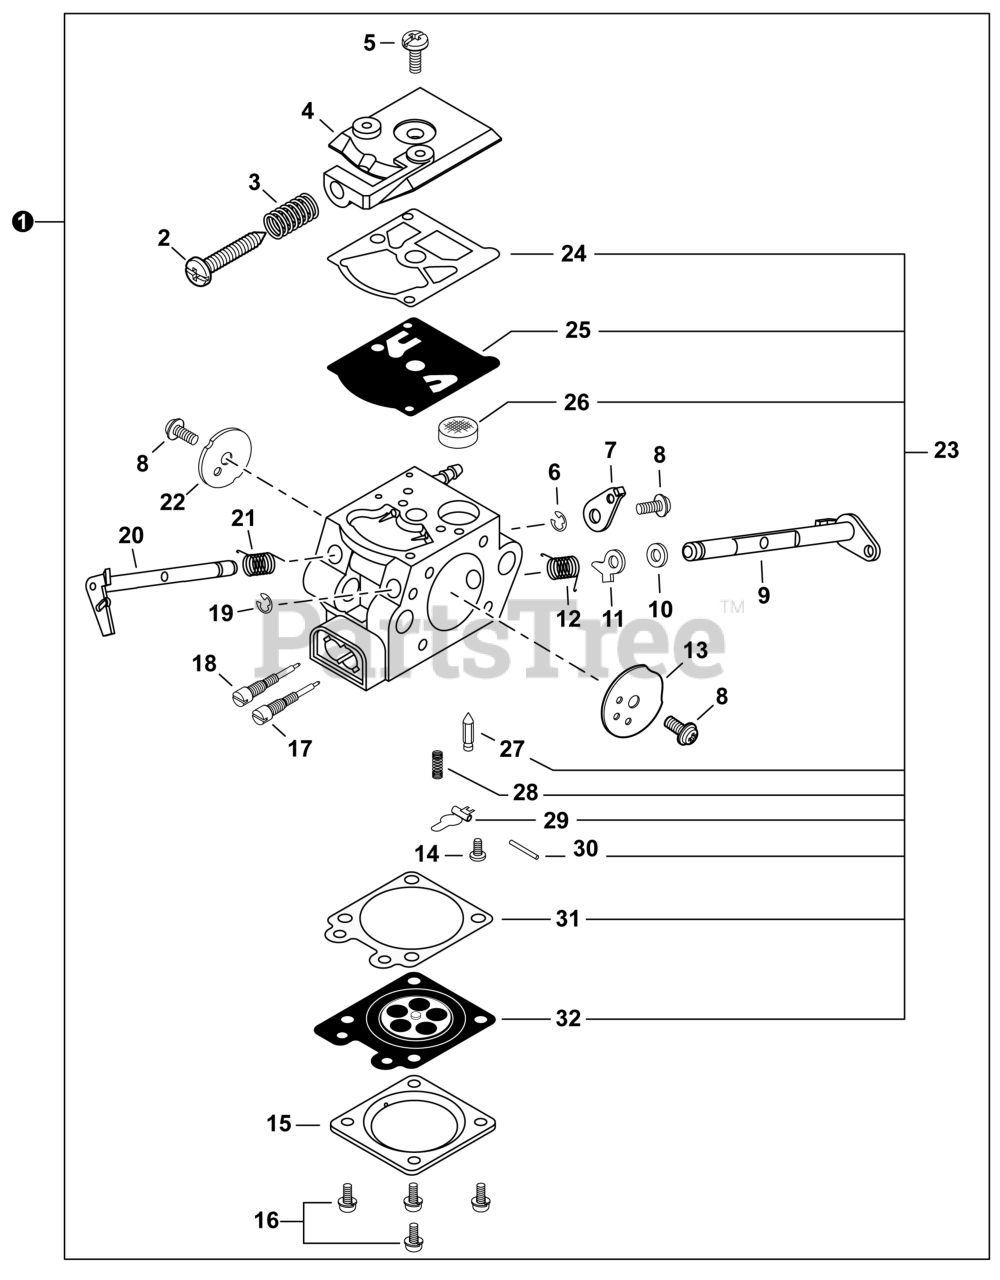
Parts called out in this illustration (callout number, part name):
1	CARBURETOR - GC-02
2	SCREW, IDLE ADJUST
3	SPRING, IDLE ADJUST
4	COVER, FUEL PUMP
5	SCREW
6	E-RING
7	LEVER, THROTTLE
8	SCREW
9	SHAFT, CHOKE
10	WASHER
11	LEVER, FAST IDLE
12	SPRING
13	VALVE, CHOKE
14	SCREW
15	COVER, METERING DIAPHRAGM
16	SCREW
17	NEEDLE, HIGH SPEED
18	NEEDLE, LOW SPEED
19	E-RING
20	SHAFT, THROTTLE
21	SPRING, THROTTLE RETURN
22	VALVE, THROTTLE
23	REPAIR KIT, CARBURETOR
24	GASKET, FUEL PUMP
25	DIAPHRAGM, PUMP
26	SCREEN, FUEL INLET
27	VALVE, INLET NEEDLE
28	SPRING, METERING LEVER
29	LEVER, METERING
30	PIN, METERING LEVER
31	GASKET, METERING DIAPHRAGM
32	DIAPHRAGM, METERING
